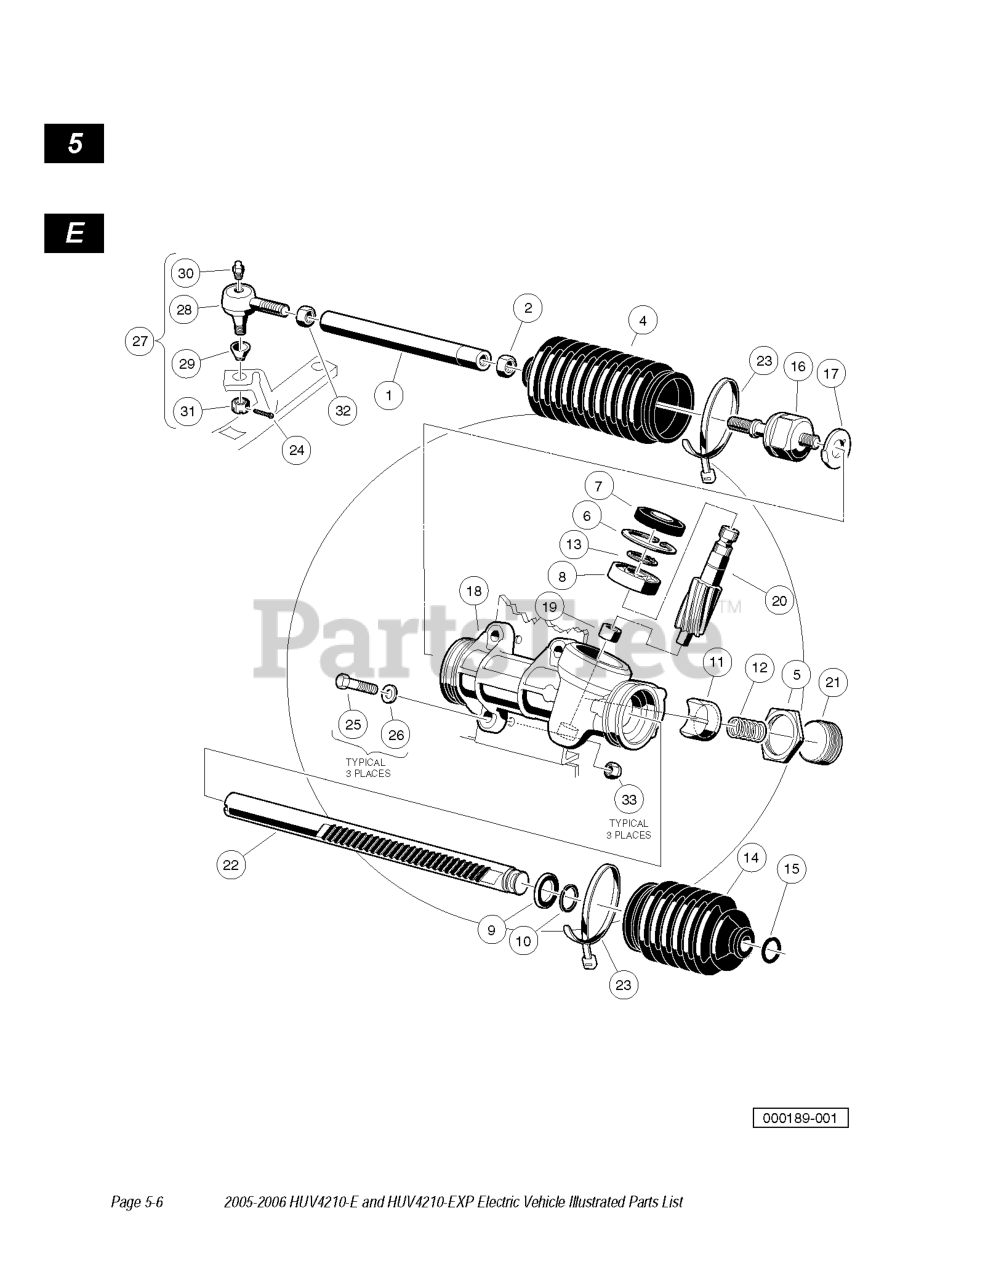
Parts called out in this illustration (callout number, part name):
1	DRAG LINK RACK & PINION
2	12MM HEX NUT
3	ASM, STEERING RACK, 3.13
4	BELLOWS, LONG
5	RACK SCREW LOCKNUT
7	SEAL, STEERING PINION DUST
8	BEARING BALL
9	STOP WASHER
10	STOP RING C - TYPE
11	SUPPORT YOKE
12	RACK GUIDE PRESSURE SPRING
13	C-TYPE STOP RING
14	BELLOWS, SHORT
15	DUST SEAL RETAINING RING
16	INNER BALL JOINT ASM
17	WASHER, TAB
23	TIE WRAP, 8" NYLON
24	PIN,CUT COTTER
25	SCREW, 3/8-16 X 1.5 HX HD CAP
26	WASHER, 3/8 FLAT
27	BALL JOINT, LH
29	SEAL, VERTICAL SOCKET DUST
30	FITTING, 1/4-28 THRD FRM GREAS
31	NUT, 3/8-24 UNF HEX THICK SLOT
32	NUT, 1/2-20 HEX
33	LOCKNUT, 3/8-16 HEX
